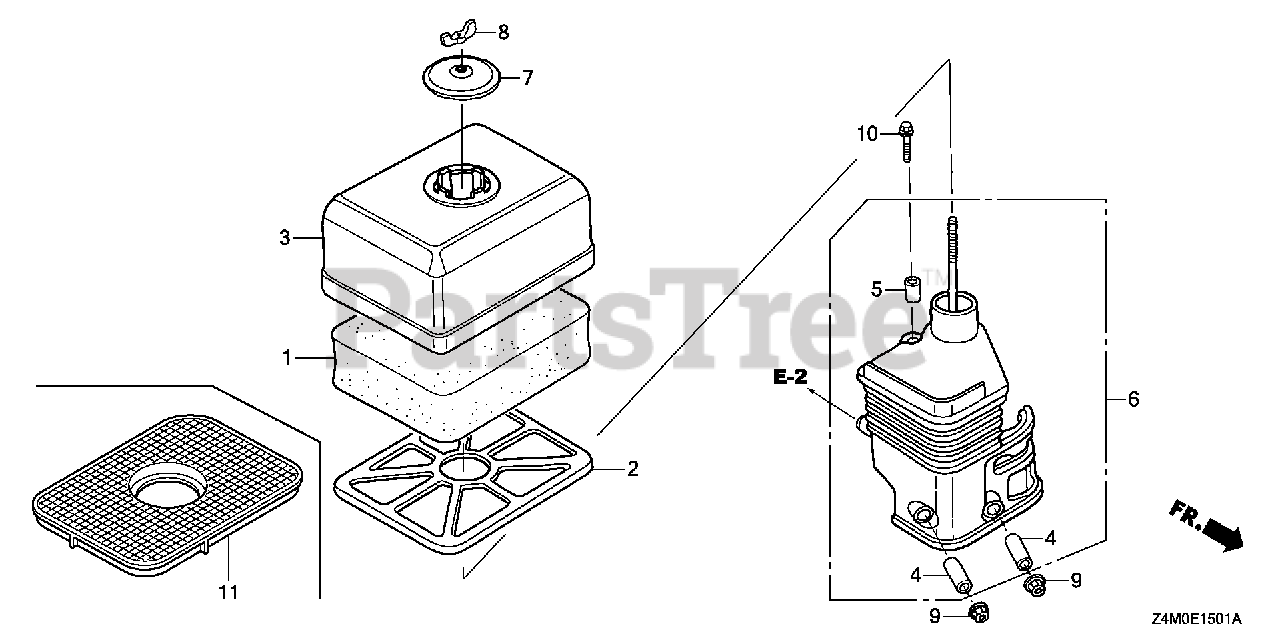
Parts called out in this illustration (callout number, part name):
1	ELEMENT, AIR CLEANER (SEMI-DRY)
3	COVER, AIR CLEANER (SEMI-DRY)
4	COLLAR, AIR CLEANER Use from Engine SN 1786085.
5	COLLAR B, AIR CLEANER
6	ELBOW, AIR CLEANER
7	CAP, CLEANER
8	WINGNUT, TOOL BOX SETTING
9	NUT, FLANGE (6MM)
10	BOLT, FLANGE (6X20)
11	GRID, AIR CLEANER
